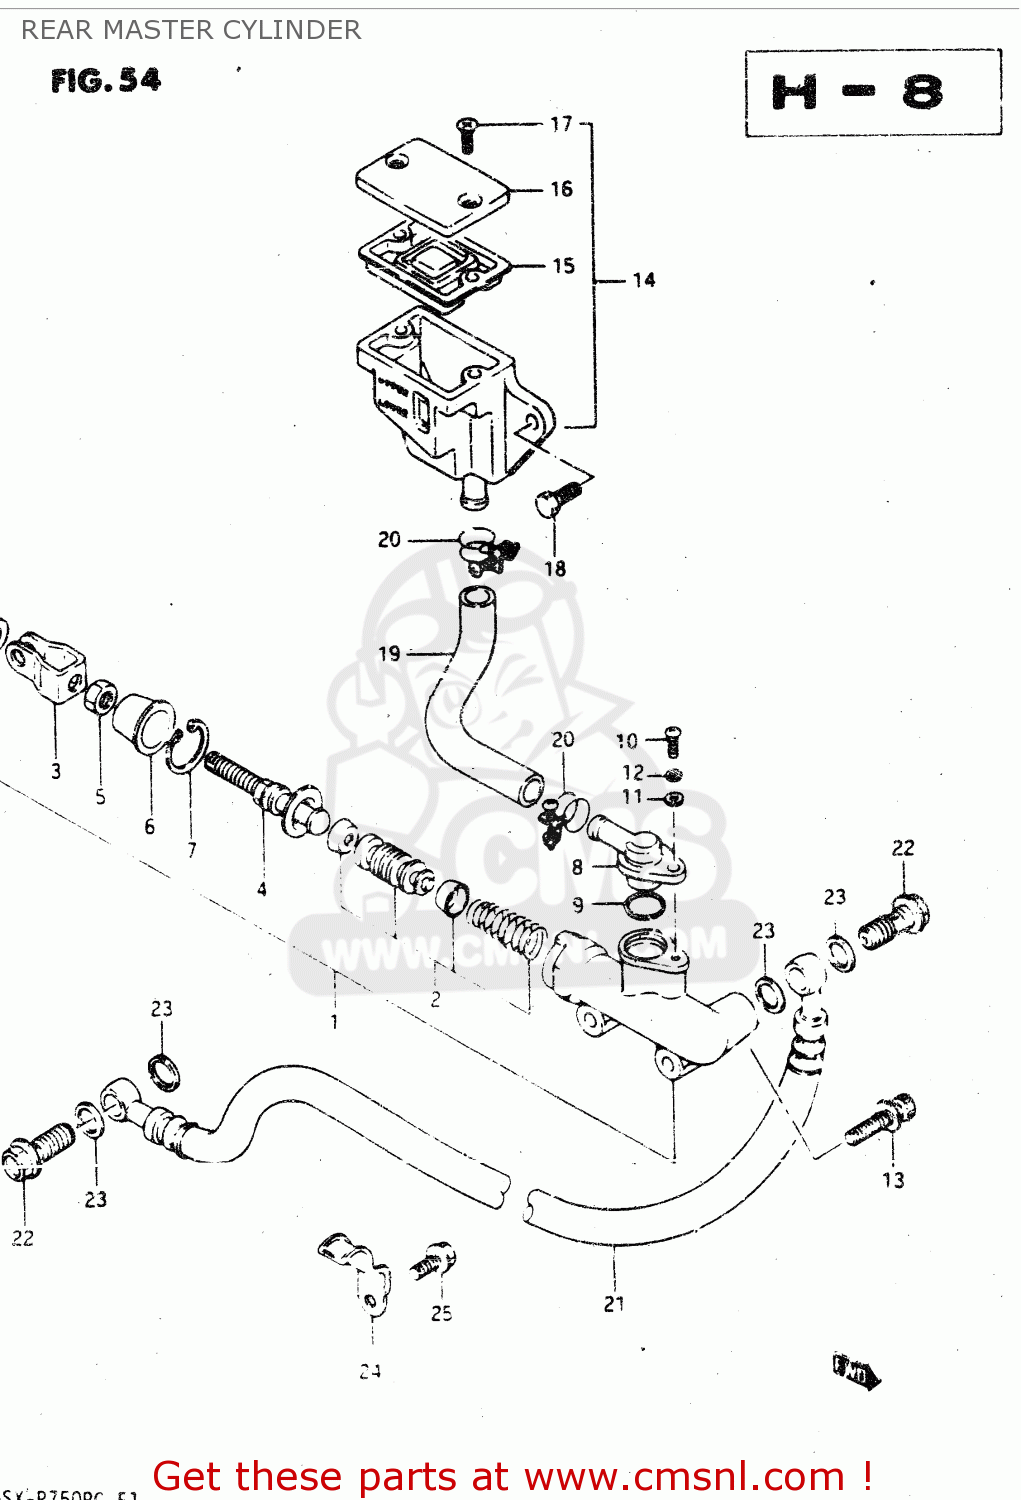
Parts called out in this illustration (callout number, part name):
1	CYLINDER ASSY,RR MASTER
2	PISTON/CUP SET
3	YOKE
4	ROD,PUSH
5	NUT
6	BOOT
7	CIRCLIP
8	CONNECTOR
9	O RING
10	SCREW
11	WASHER
12	LOCK WASHER
13	BOLT
14	TANK ASSEMBLY,RESERVOIR
15	DIAPHRAGM
16	CAP
17	SCREW
18	BOLT
19	HOSE,RESERVOIR TANK
20	CLAMP
21	HOSE,REAR BRAKE
22	BOLT UNION
23	WASHER(10X15X1.5)
24	CLAMP
25	BOLT
